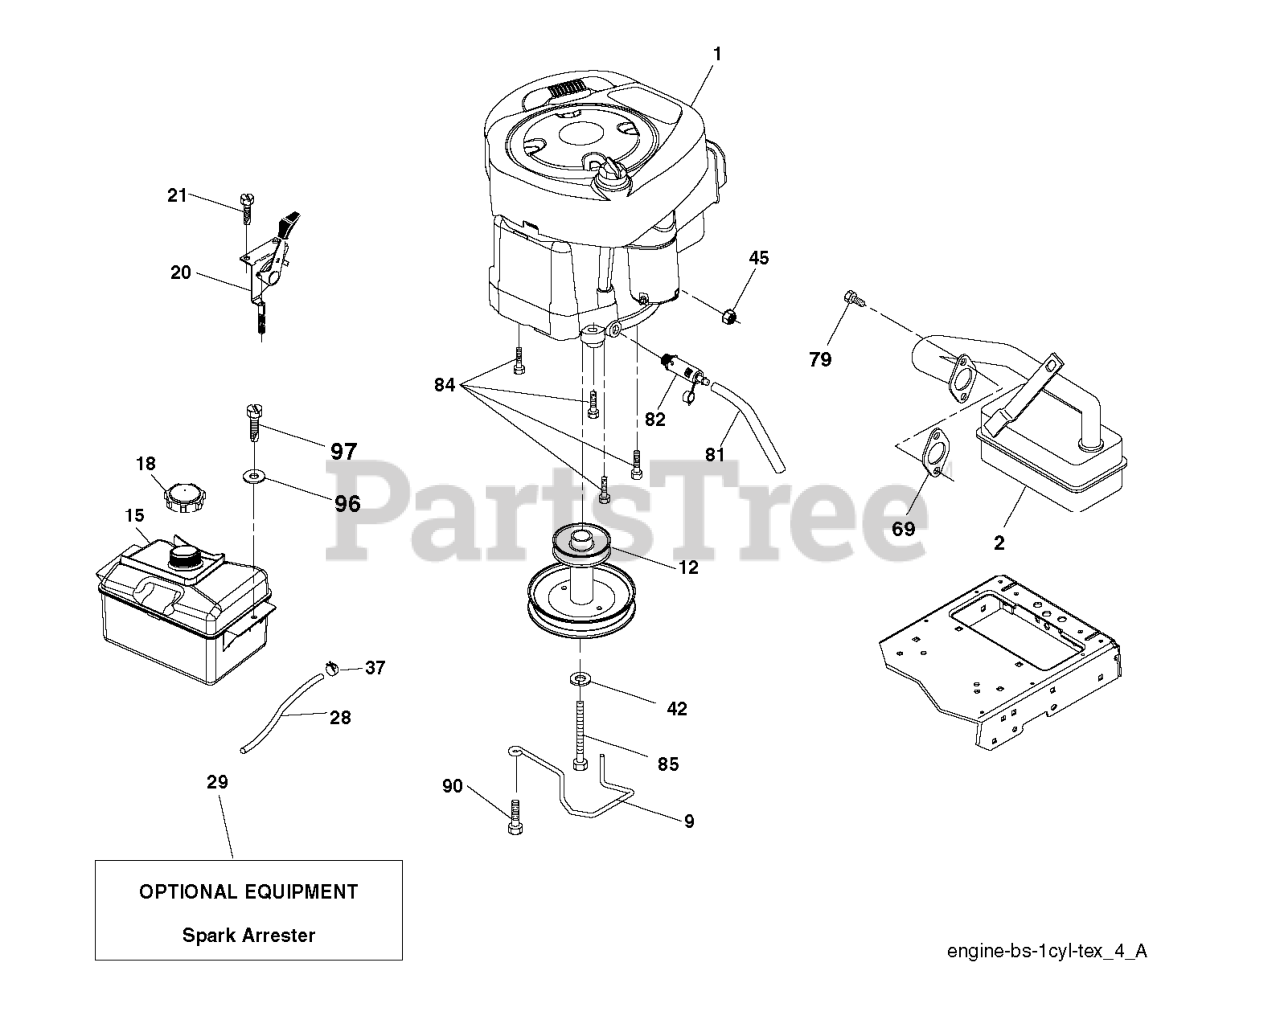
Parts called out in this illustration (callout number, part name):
2	MUFFLER.LT.BRIGGS.14HP.IC/OHV
9	KEEPER.BELT.ENGINE.3.25 (3 2)
12	PULLEY ENGINE
15	RP TANK FUEL FRT 1.5 GAL
18	FUEL CAP
20	CONTROL.TH/CK.COBRA.KO
21	SCREW
28	LINE.FUEL.20"FRONT.EMI
29	KIT.SPARK ARRESTOR 794945 B&S
37	HOSE CLAMP
42	LOCKWASHER
45	NUT
69	REPL BY 532 27 22-93
79	SCREW.SOCKET HD.5/16-1
81	TUBE, DRAIN OIL ASM.
82	PLUG DRAIN OIL EASY
84	SCREW.3/8-16
85	BOLT HEX 7/16-20X4-1/4"
90	SCREW 3/8-16X1
97	SCREW HEXWSHR 1/4-20X3/4
